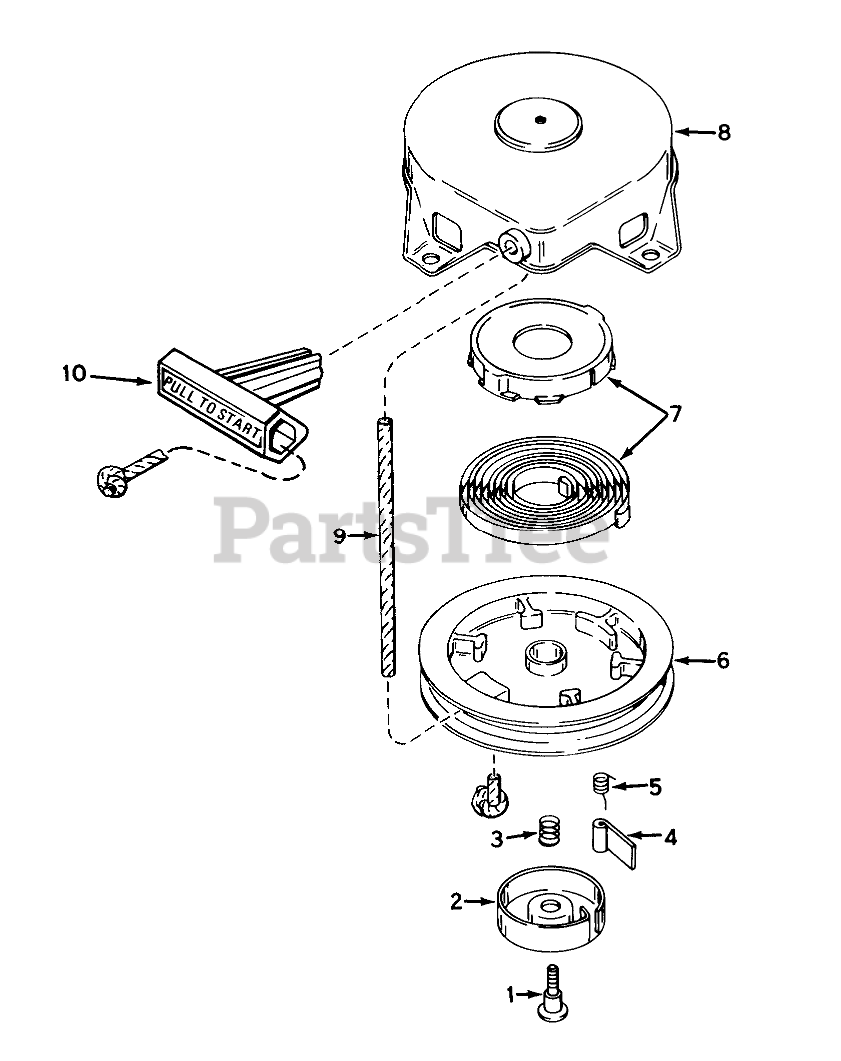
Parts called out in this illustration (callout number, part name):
2	Retainer
3	Spring-Brake
4	Dog-Starter
5	Spring-Dog
7	Spring & Keeper Assy
8	Housing-Starter
9	Rope-Starter (98 cut to length)
10	Handle-Starter
